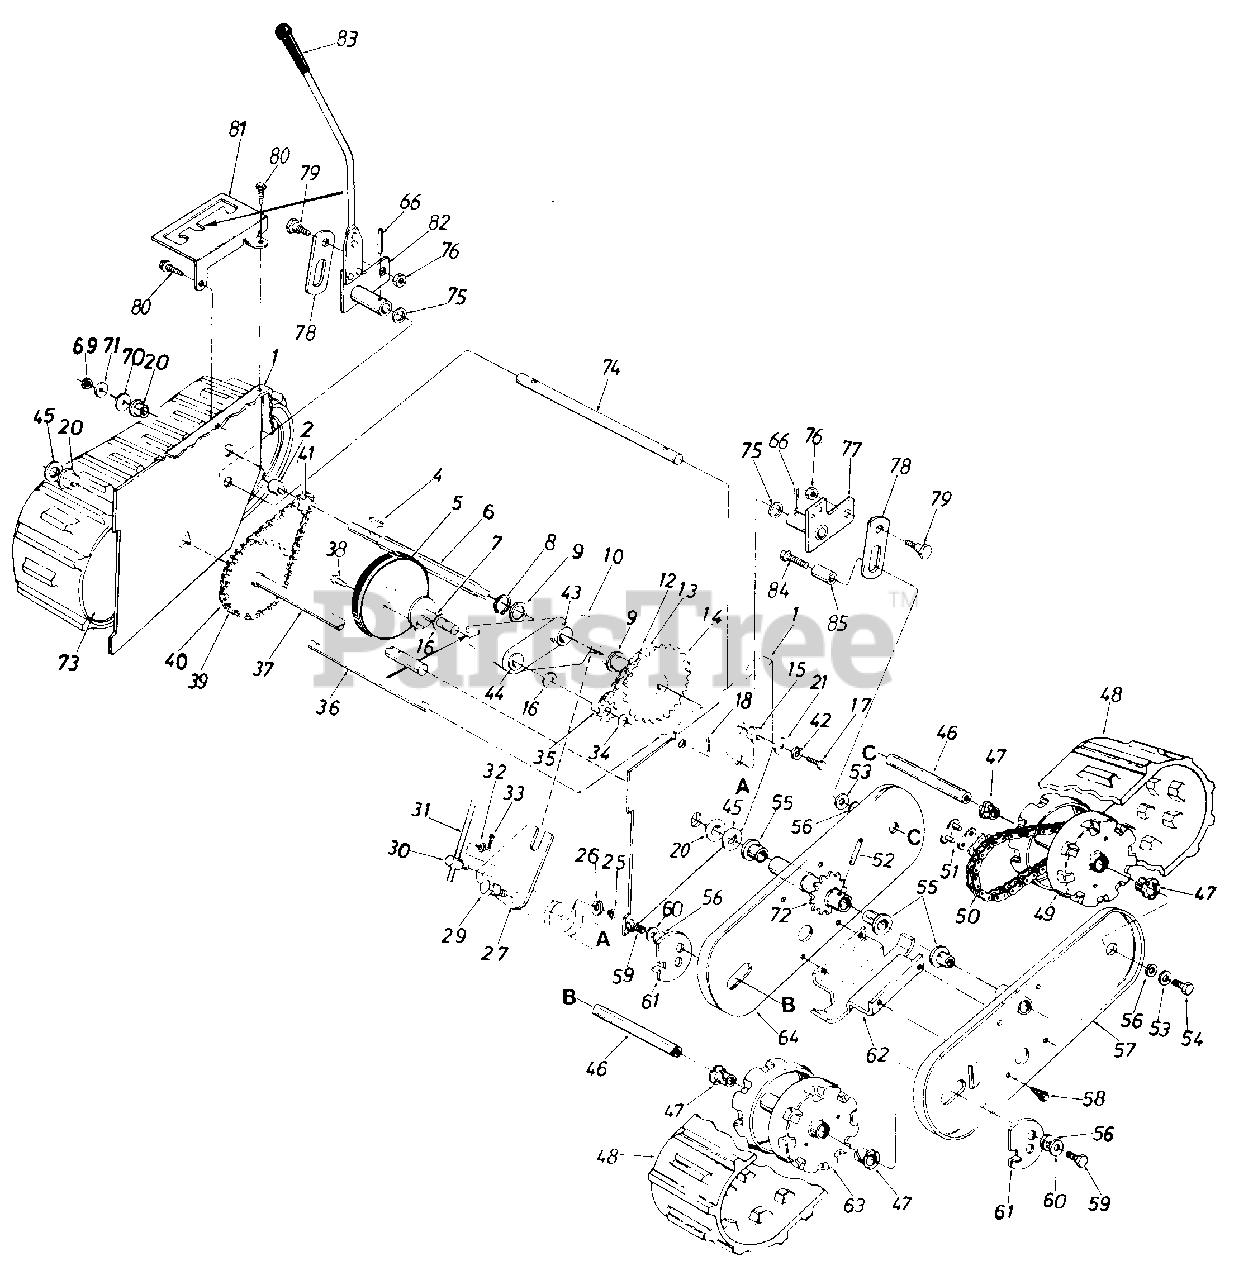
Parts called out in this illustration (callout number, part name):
1	Frame Ass'y.
2	Spacer.50" I.D. x .75" O.D. x .78" Lg.
4	#4 Hi-Pro Key 3/32 x 5/8" Dia.
5	Friction Wheel Ass'y.
6	Hex Shaft
7	Friction Wheel Mounting Plate Ass'y.
8	Snap Ring 1.00" Dia. Shaft
9	Fl-Wash 1.00 x 1.63" O.D. I x.03
10	Sliding Bracket Ass'y.
12	#41 Chain 1/2" Pitch x 35 Links
13	Master Link for #41 Chain
14	32 Teeth Sprocket Ass'y.
15	Hex Flange Brg. .630" I.D.
16	Fl-Wash. .62" I.D. x 1.00" O.D. x .06
17	Hex Lock Bolt 5/16-18 x .62" Lg.
18	Coter Pin 3/32" Dia. x .75" Lg. *
20	Hex Flange Brg. .751" I.D.
21	Fl-Wash. .34" I.D. x 1.12" O.D. x .125
25	Hex Jam Nut 3/8-16 Thd.*
26	L-Wash. 3/8" I.D.*
27	Shifting Linkage Bracket
29	Shld. Bolt .625" Dia. x .170"
30	AdJustment Ferrule
31	Shifting Rod 5/16" Dia. x 32.50" Lg.
32	Fl-Wash. .34" I.D. x .64" O.D. x .06
33	Coter Pin 3/32" Dia. x .75" Lg. *
34	Snap Ring .562" Dia. Shaft
35	Sprocket 7 Teeth x .50" Pitch I
36	Shaft ,50"1Dia. x 9.50" Lg.
37	32 Teeth Wheel Shaft Ass'y.
38	Hex Wash. Hd. Self-Tap Scr. 5/16-24 x .50" Lg.
39	#420 Chain 1/2" Pitch x 39 Links
40	Master Link for #420 Chain
41	8 Teeth Center Sprocket
42	L-Wash. 5/16" I.D.
43	Plastic Bearing
44	Bronze Bearing
45	Fl-Wash. .76" I.D. x 1.49 O.D.
46	Wheel Shaft 5/8 x 4.25" Lg.
47	Flange Brg. .632" I.D.
48	Snow Track 5" x 48"
49	Drive Wheel Ass'y.
50	Chain #420 x 50 Pitch x 37 Links
51	Master Link #420
52	Spring Pin Spir. 1/4" Dia. x 1.50" Lg.
53	Bell-Wash. .345" I.D. x .88" O.D.
54	Hex Bolt 5/16-24 x .62" Lg.
55	Flange Brg. .757" I.D.
56	Fl-Wash. .510" I.D. x 1.0" O.D.
57	Outer Plate Ass'y.L.H.
58	Hex Wash. S-Tap Scr. 1/4-20 x .50" Lg.
59	Hex Bolt 5/16-24 x .62" Lg.
60	Bell-Wash. .345" I.D. x .88" O.D.
61	Track Adjuster
62	Skid Shoe
66	Spring Pin 1/4" x 1.25" Lg.
69	Hex Ins. L-Nut 1/2-20 Thd.
70	Fl-Wash. .53 I.D. x 1.25 O.D. x .10
71	Bell-Wash. .50 I.D. x 1.0 O.D. x .075
72	17 T Sprocket Hub Ass'y.
73	Inner Plate Ass'y.R.H.
74	Track Lock Axle
75	Fl-Wash. 5/8 I.D. x 1" O.D.
76	Hex L-Nut 3/8-16 Thd.
77	Pivot Arm Ass'y.L.H.
78	Sloted Link
79	Shld. Bolt .625" Dia. x .217
80	Hex Wash. AB-Tap Scr,. 5/16 x .75" Lg.
81	Position Selector Plate
82	Track Lock Handle Ass'y.
84	Hex Bolt 5/16-24 x 1.25" Lg. (Grade 5)
85	Spacer.325" I.D.
